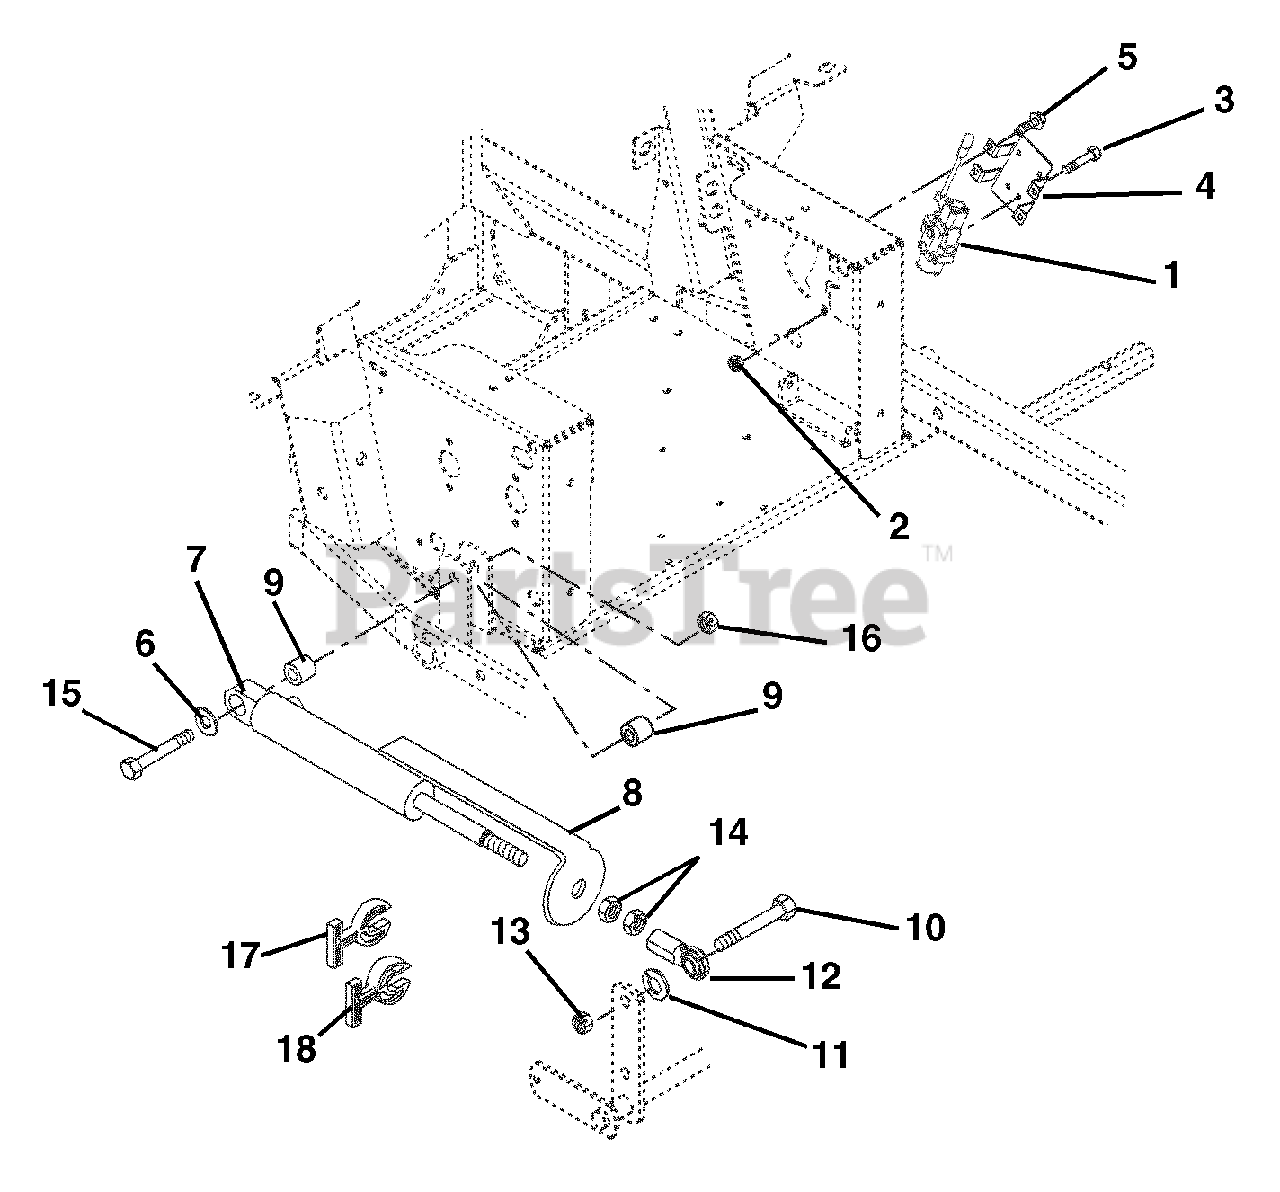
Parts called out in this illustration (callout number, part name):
1	Valve, Hydraulic
2	Nut-Locking-Nylon .31-18
3	Bolt-Hex .31-18 x 2.25 Grade 5
4	Bracket, Valve Mounting
5	Screw-Tapping .38-16 x .50 Hex Washer Head
6	Washer-Flat-Steel .515 x 1.625 x .25
7	Cylinder-Hydraulic Lift
8	Strap-Height of Cut Indicator
9	Bushing .516 x 1.00 x 1.05
10	Bolt-Hex .62-11 x 2.25 Grade 8
11	Washer-Lock .62 x .156
12	Rod End-Right Hand-Female .625
13	Nut-Locking-Center .62-11
14	Nut-Jam .625-18
15	Post, Cylinder Stop
16	Nut-Locking-Center .50-13
17	Stop, Cylinder .34 Thick
18	Stop, Cylinder .68 Thick
